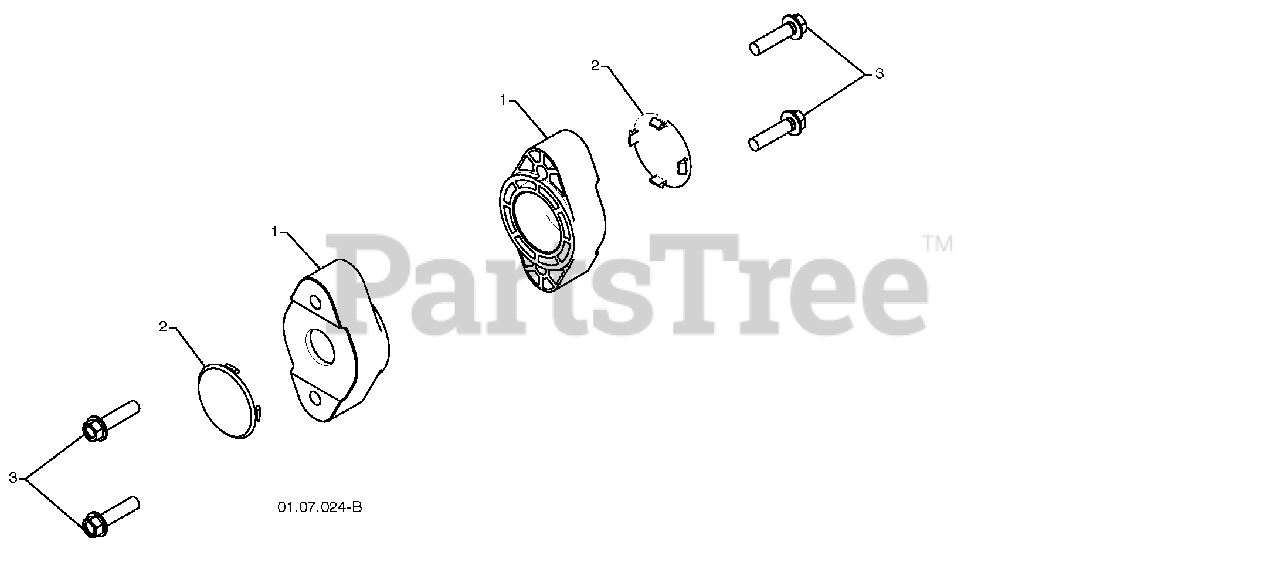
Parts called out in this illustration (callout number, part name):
1	AUGER BEARING
2	BEARING PLUG
3	SCREW 5/16-18 X 1.00
